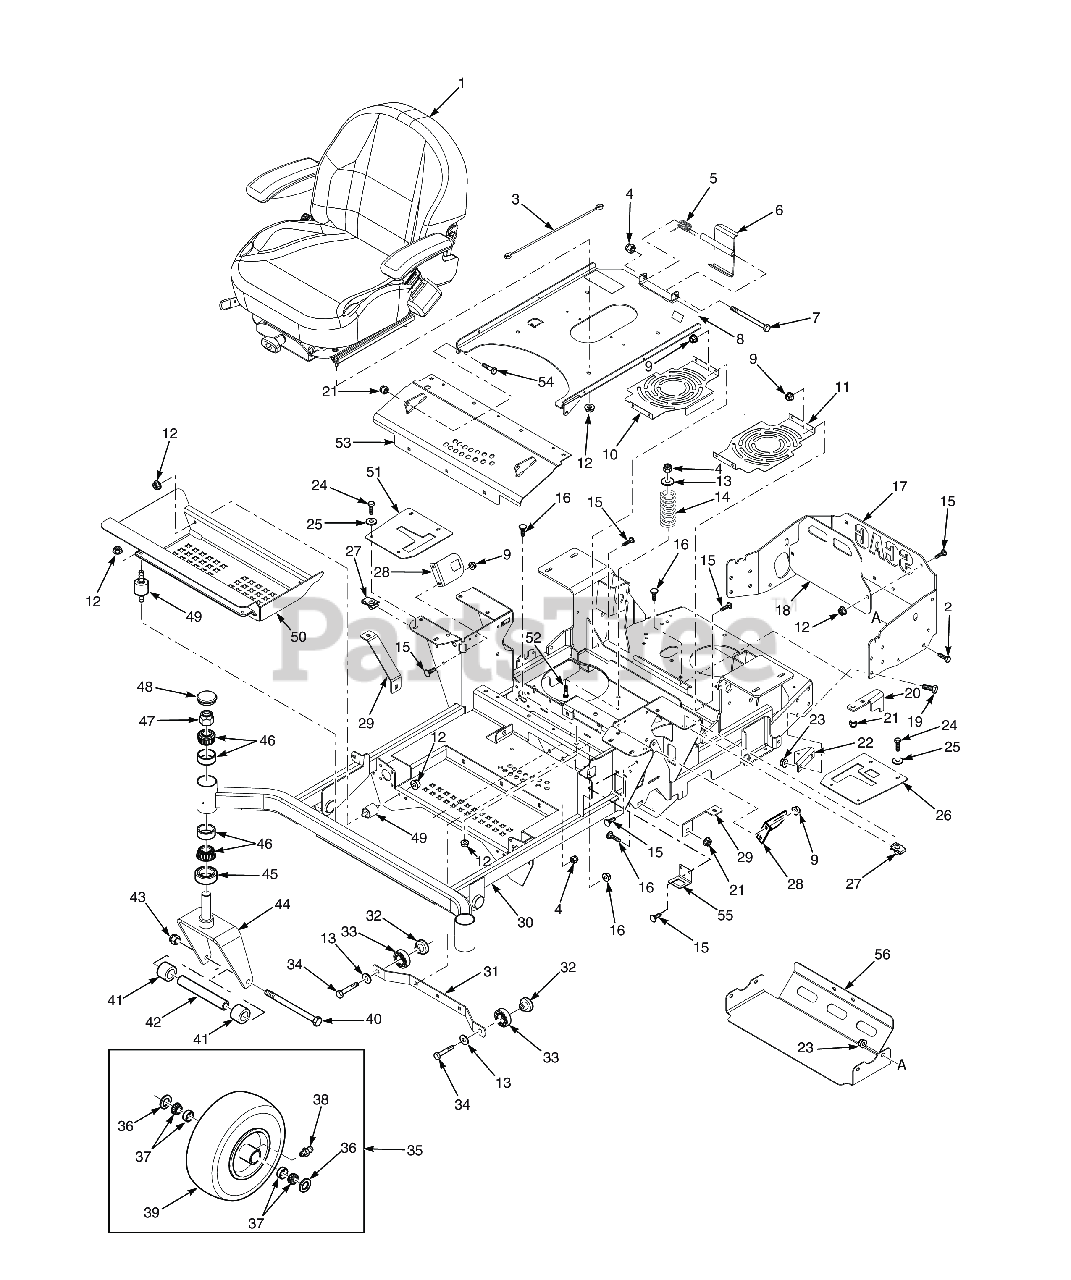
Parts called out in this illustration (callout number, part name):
1	Seat Assembly
2	Bolt, Hex Head, 3/8-16 x 3/4"
3	Cable, Seat Stop
4	HEX NUT, ELASTIC STOP LOCK, 3/8-16
5	Spring, Seat Latch
6	Weldment, Seat Latch
7	Bolt, 3/8-16 x 6.00" Hex Head
8	Seat Plate Weldment
9	NUT, 1/4-20 SERRATED FLANGE HEX HEAD
10	Fan Cover, RH
11	Fan Cover, LH
12	Nut, Serrated Flange 5/16-18 (Right Front Engine Mounting, Briggs and Kohler Only)
13	Flatwasher, 3/8" Special (.391 x .938 x .105)
14	Spring, Seat
15	SERR. FLG. HEX HEAD CAPSCREW, 5/16-18 X 3/4
16	Bolt, 5/16-18 x .75 RHSN Carriage
17	Bumper - SPZ
17	Bumper, (Black)
18	Guard, Engine, (Scag Gold)
18	Guard, Engine
19	Bolt, Hex Head, 3/8-16 x 1 Gr. 5
20	Bracket, Anti-Rotation
21	HEX NUT, ELASTIC STOP LOCK, 3/8-16
22	Bracket, Dump Mounting
23	NUT, 3/8-16 SERRATED FLANGE HEX HEAD
24	Capscrew, Hex Head 1/4-20 x 1"
25	Flatwasher, 1/4" (.312 x .750 x .065")
26	Control Plate w/Decal, LH
27	Bolt, Hex Head 3/8-16 x 1"
28	Bracket, Switch Mount
29	Bracket, Tank Mount, SFZ52
30	Mainframe Assy., w/Decals - SPZ52
30	Mainframe Assy., w/Decals (Black) - SPZ52
31	Support, Deck Guide
32	Spacer, Bearing
33	Bearing
34	Capscrew, Hex Head 3/8-16 x 2-1/2"
35	Wheel Assy(Inc.items 20, 42, 43, 54, 55)
35	Wheel Assembly, (Black)
36	Roller Bearing, Short
37	Bearing, Tapered Roller
38	Fitting, Grease
39	Tire, 13 x 6.50 4-Ply (61A, 72A)
39	Rim Assembly, 61A & 72A (Inc. item 55)
39	Rim, (Black)
40	Bolt, Hex Head 1/2-13 x 9-1/2" (61V & 72A/VS)
41	Spacer, Caster Wheel
42	Sleeve, Caster Wheel (61V, 72A/VS)
43	HEX LOCKNUT, ELASTIC STOP, 1/2-13
44	Yoke, Front Caster Wheel (61")
44	Yoke Weldment, (Black))
45	Seal, 2.00" O.D. x 1.625" Bore
46	BEARING & CUP, TAPERED SPINDLE
47	Nut, Hex Elastic Stop 1.0"-14
48	Cap, Grease
49	Rubber Isolator
50	Footplate Weldment, SFZ52
50	Footplate Weldment, (Black) - SPZ52
51	Control PLate w/Decal, RH
52	SHORT SQ. NECK CARRIAGE BOLT, 3/8-16 X 1-1/4"
53	Deck Lift Cover w/Decal, SPZ52
53	Deck Lift Cover w/Decal, (Scag Gold Logo) - SPZ52
54	BOLT, HEX HEAD 5/16-18 X 3-3/4"
55	Switch Bracket
56	Heat Shield, (Scag Gold)
56	Heat Shield
